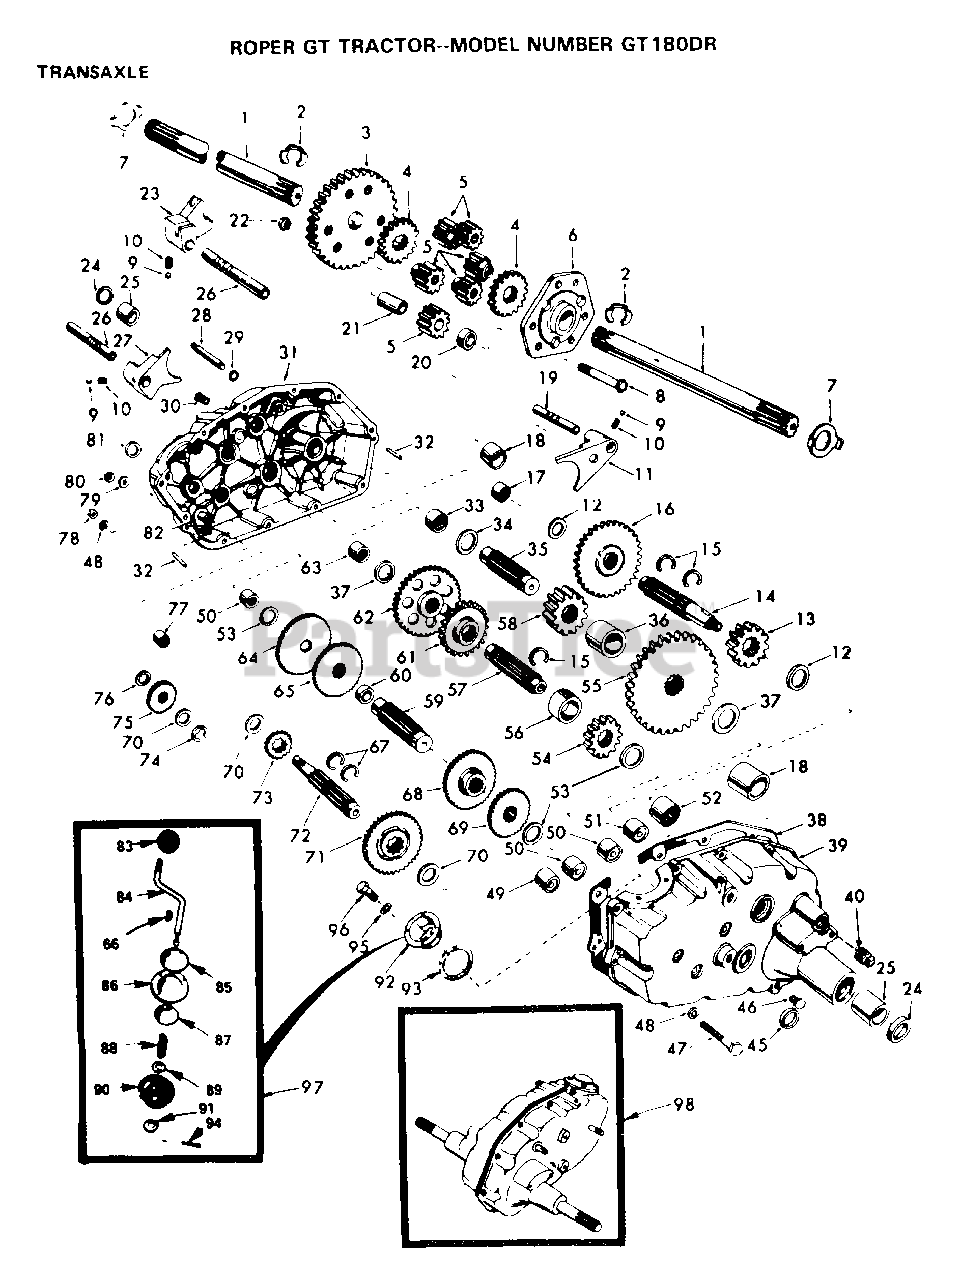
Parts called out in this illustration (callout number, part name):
1	SHAFT.AXLE.T
3	FINAL GEAR T
4	DIFF GEAR T
5	DIFF PINION T
6	DIFF CARRIER T
8	BOLT
11	SHIFT FORK T
12	WASHER .T
13	RED PINION T
14	GEAR SHAFT T
15	SNAP RING T
16	GEAR T
17	"T, BEARING"
18	BEARING
20	SPACER T
21	PINION RS
22	GRIPCO NUT
23	SHIFT FORK T
24	OIL SEAL STD
25	BRNG. T
27	FORK T
28	SHIFT SHAFT GTV
29	SEAL T
32	PIN T
33	NEEDLE BRNG T
34	RACE T
35	GEAR SHAFT T
37	RACE T
45	SEAL T
47	HEX BOLT
49	"TI, BEARING"
50	NEEDLE BRNG T
51	NEEDLE BRNG T
52	"STD, BEARING"
53	BRNG RACE
54	RED PINION T
55	RED GEAR T
56	PINION SPACER T
57	GEAR SHAFT T
58	FINAL PINION T
59	GEAR SHAFT T
60	SPACER T
61	RED PINION T
62	RED GEAR T
63	RACE T
64	LOW SPEED GEA T
65	REVERSE GEAR T
66	KEY T
67	RING STD
68	INTERMED GEAR T
70	"T, BEARING"
71	CLUSTER GEAR T
72	INPUT SHAFT T
73	LO SPEED PINION T
75	IDLER GEAR T
76	WASHER T
77	BRNG T
78	NUT.HEX.5/16-18
79	WASHER T
80	NUT
81	SEAL STD
84	GEAR SHIFT LVR T
85	CAP T
86	COVER AND PIN T
87	GUIDE BALL T
88	SPRING TI
89	WASHER
91	WASHER
92	GEAR SHIFT GA T
93	GASKET T
94	COTTER PIN
95	LOCKWASHER
96	BOLT
97	GEAR SHFT LVR T
98	TRANSAXLE GTV
